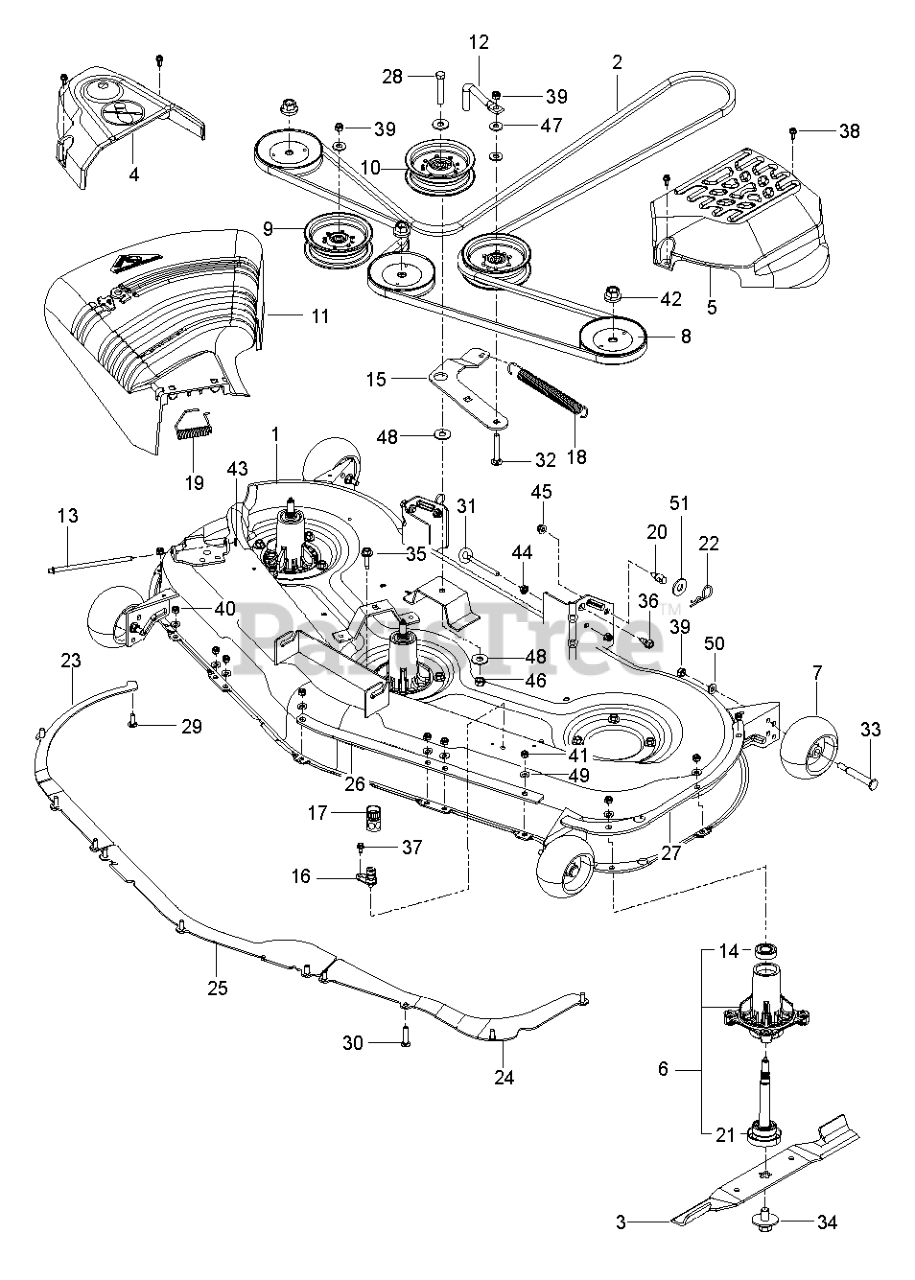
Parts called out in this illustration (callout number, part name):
1	WHEEL.STEER.HUSQ.SR.498.OVMLD
2	AXLE.CAST.IRON
4	SPINDLE.WELDED.LH.16"TEX
5	SPINDLE.WELDED.RH.16"TEX
6	THRUST WASHER
9	CAP.SPINDLE.BLACK
14	WASHER, LOCK 3/8
15	NUT CROWNLOCK 3/8-24
16	SHAFT, STEERING
19	PLATE.STEER.DDL.NLT/NG
21	ADAPTER.WHEEL.STEER.SPLND.ALUM
22	BEARING.SUBASM.SHAFT.STEER.LOW
26	INSERT.CAP.WHL.STRG.HUSQ.PREM
28	SCREW, 3/8-16X3/4
35	GEAR.SECTOR.PLATE.DDL.
45	WASHER 9/16"ID, 2 3/8"OD
50	NUT LOCK FLG 3/8-16 UNC
53	WASHER.HARDENED
55	SPACER.BRACE.AXLE
58	BOLT.SHOULDER.SECTOR.P
59	WASHER.THURST.SECTOR.S
60	NUT FLANGE LOCK 5/8-11
61	DRAGLINK.LH.BALLSTUD.D
62	DRAGLINK.RH.BALLSTUD.D
63	SCREW
64	RETAINER.CLIP.SPRING.S
65	BRACE.AXLE.FRONT.NLT/N
66	BOLT HEX FGHD 7/16-14 X 3 SERR
67	BUSHING.PM.FRONT AXLE
68	NUT.LOCK.FLANGE.7/16
69	WASHER.1.5X.505X.118
70	BRACKET.FRT.DECK.SUSP.RR.MT431
75	PINION.ZINC PLATED
76	SCREW HEAD SOCKET LRVB
78	THRUST WASHER
122	CAP.GEAR.SECTOR.TEX
